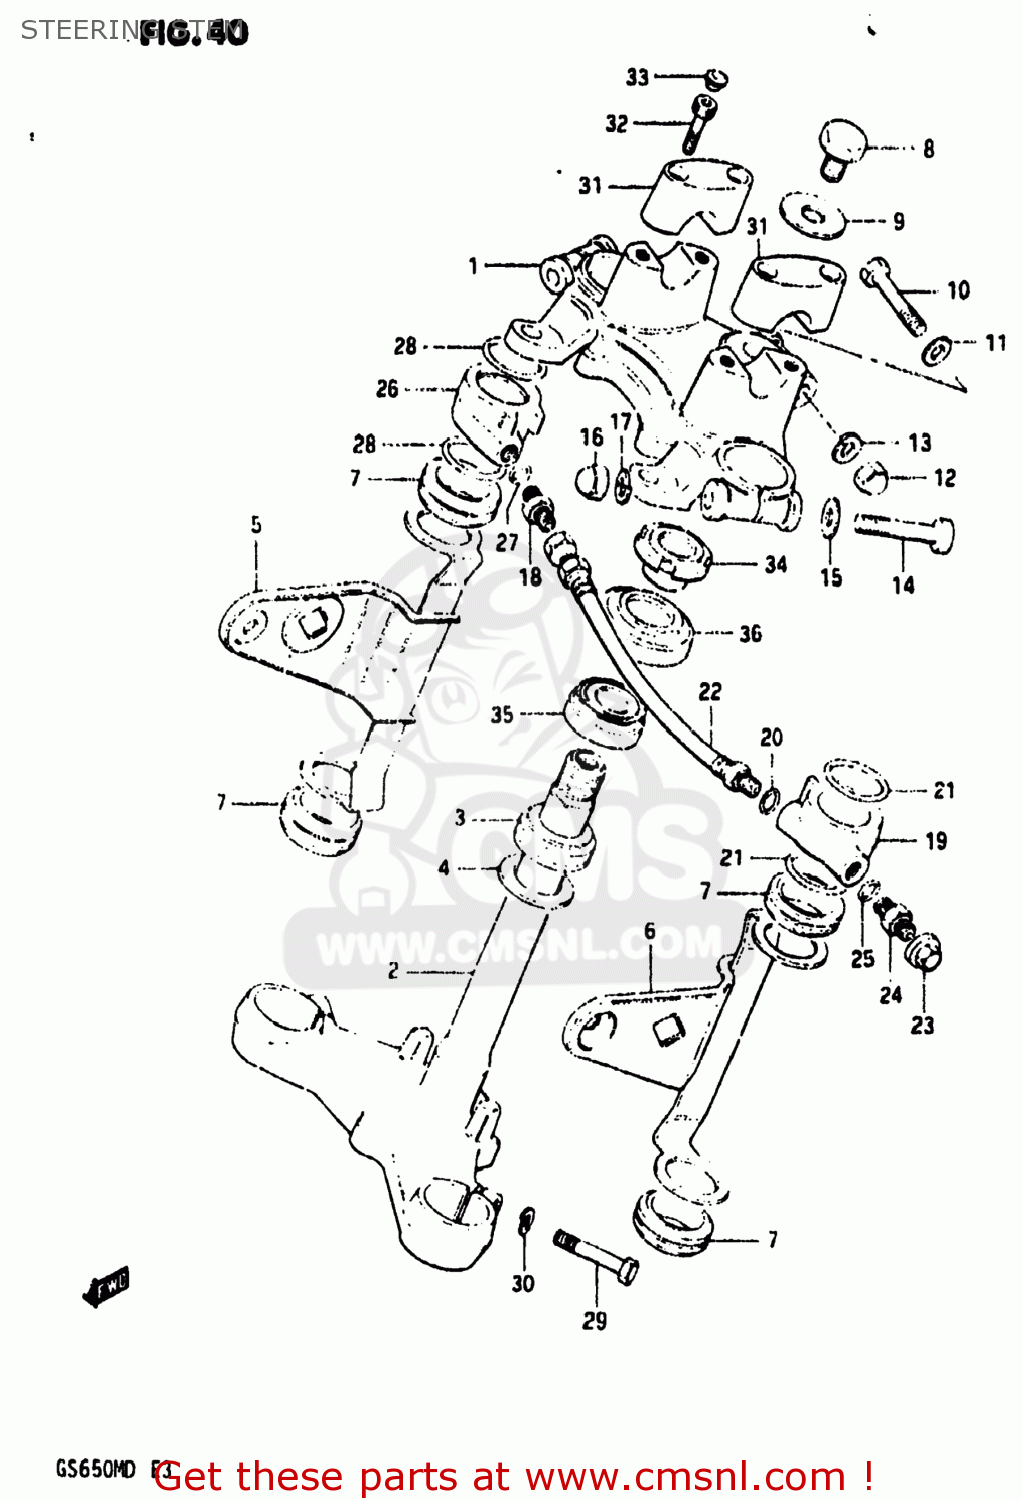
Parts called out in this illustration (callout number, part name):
1	HEAD,STEERING STEM
2	STEM,STEERING
3	BEARING
4	WASHER,THRUST
5	BRACKET,HEADLAMP,RIGHT
6	BRACKET,HEADLAMP,LEFT
7	CUSHION,HEADLAMP BRACKET
8	BOLT,STEERING STEM HEAD
9	WASHER
10	BOLT 8X50
11	WASHER
12	NUT
13	LOCK WASHER
14	BOLT 10X55
15	WASHER
16	NUT
17	LOCK WASHER
18	CONNECTOR
19	JOINT,AIR,LEFT
20	O-RING
21	O RING
22	JOINT,AIR TURBO
23	CAP,FRONT FORK AIR VALVE
24	VALVE,AIR
25	O-RING
26	JOINT,AIR,RIGHT
27	O-RING
28	O RING
29	BOLT 10X40
30	LOCK WASHER
31	HOLDER,HANDLEBAR(BLACK)
32	BOLT
33	CAP(OD:14.5)
34	NUT,STEERING STEM
35	TAPER,ROLLER BEARING
36	DUST SEAL,STEERING UPR
